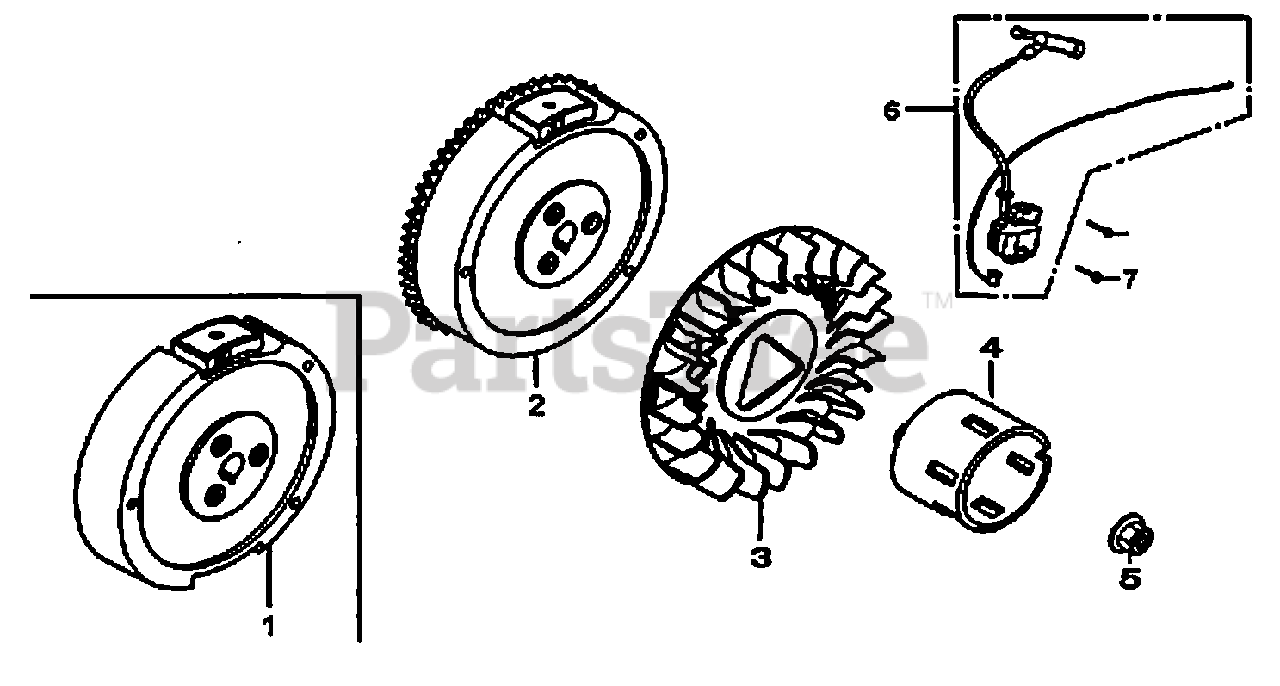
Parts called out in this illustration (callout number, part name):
1	FLYWHEEL COMP.
3	FAN COOLING
4	PULLEY, STARTER
5	NUT SPECIAL, M16
6	COIL ASSY., IGNITION
7	BOLT, FLANGE, M6X25
